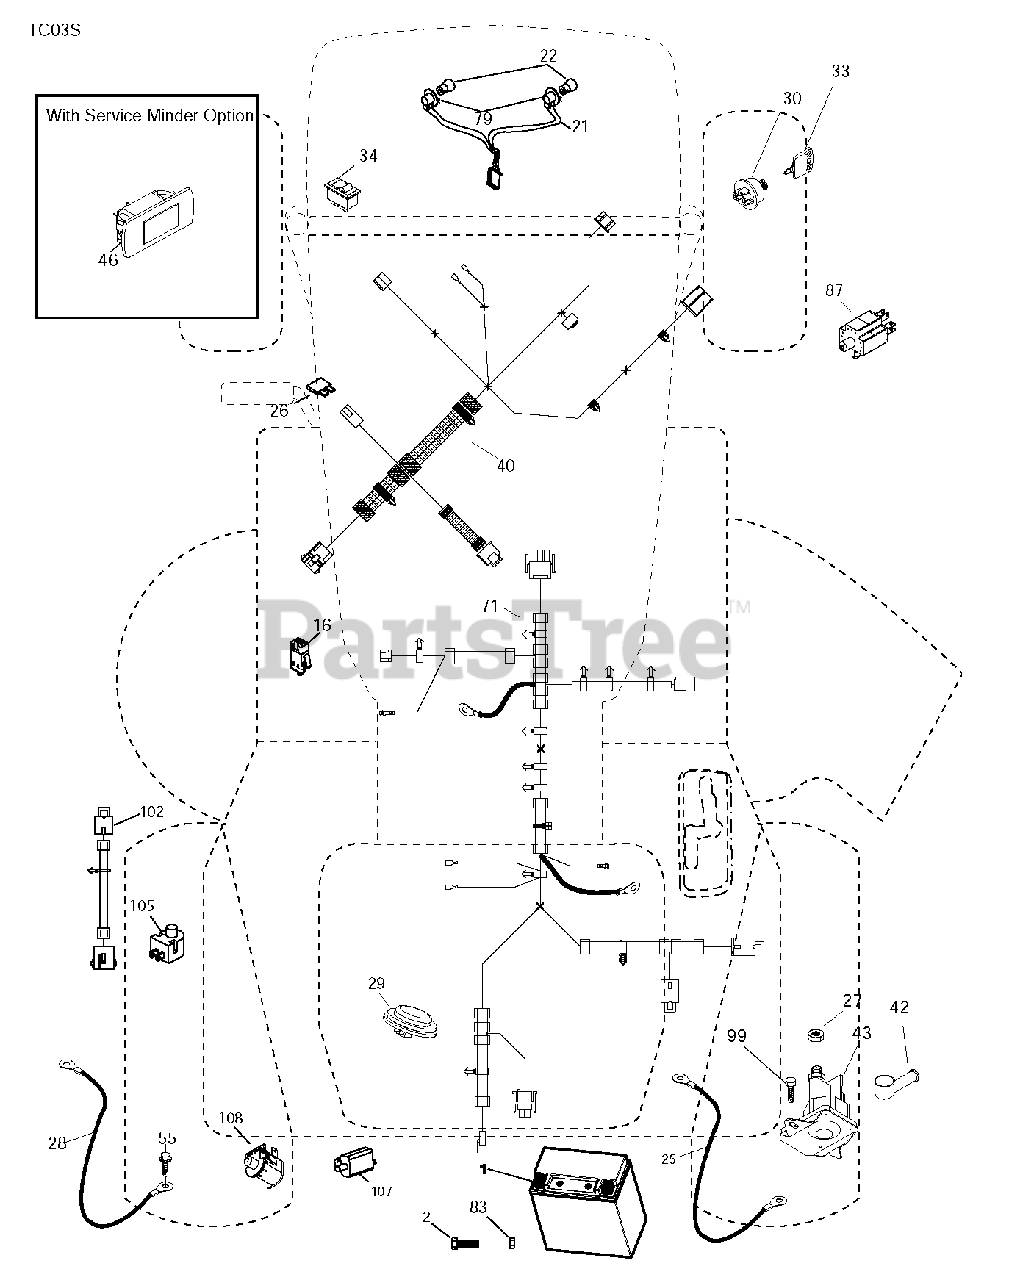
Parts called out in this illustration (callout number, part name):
1	BATTERY BATTERY 14AH 12V LEOC
2	SCREW.HEX.HEAD.CAP.M6 X1.12W
16	SWITCH INTERLOOK PUSH-IN
21	HARNESS.LIGHT W/4152J BULBS
25	CABLE BATTERY CABLE
26	FUSE 20AMP
27	NUT
29	SWITCH.SEAT.DELTA.OPC.
30	SWITCH.IGN.DELTA.W.LGH.ROS
33	KEY.CHAIN.BLISTER.PACK.GEN.INT
40	RP HARNESS.ELECTRICAL.DASH.SRD
42	TERMINAL COVER
43	SOLENOID.W/BRASS.PLUNGER
55	SCREW 5/16"
79	BULB HOLDER ASM.
83	NUT NUT SQUARE
87	RP SWITCH.RAILMOUNT.NO-NC-NC
99	SCREW
102	HARNESS PIGTAIL PCH TEX ROS
105	REVERSE SWITCH
107	.WITCH.FULL BAGGER.INDICATOR
108	SWITCH.SNAPMOUNT.NC
